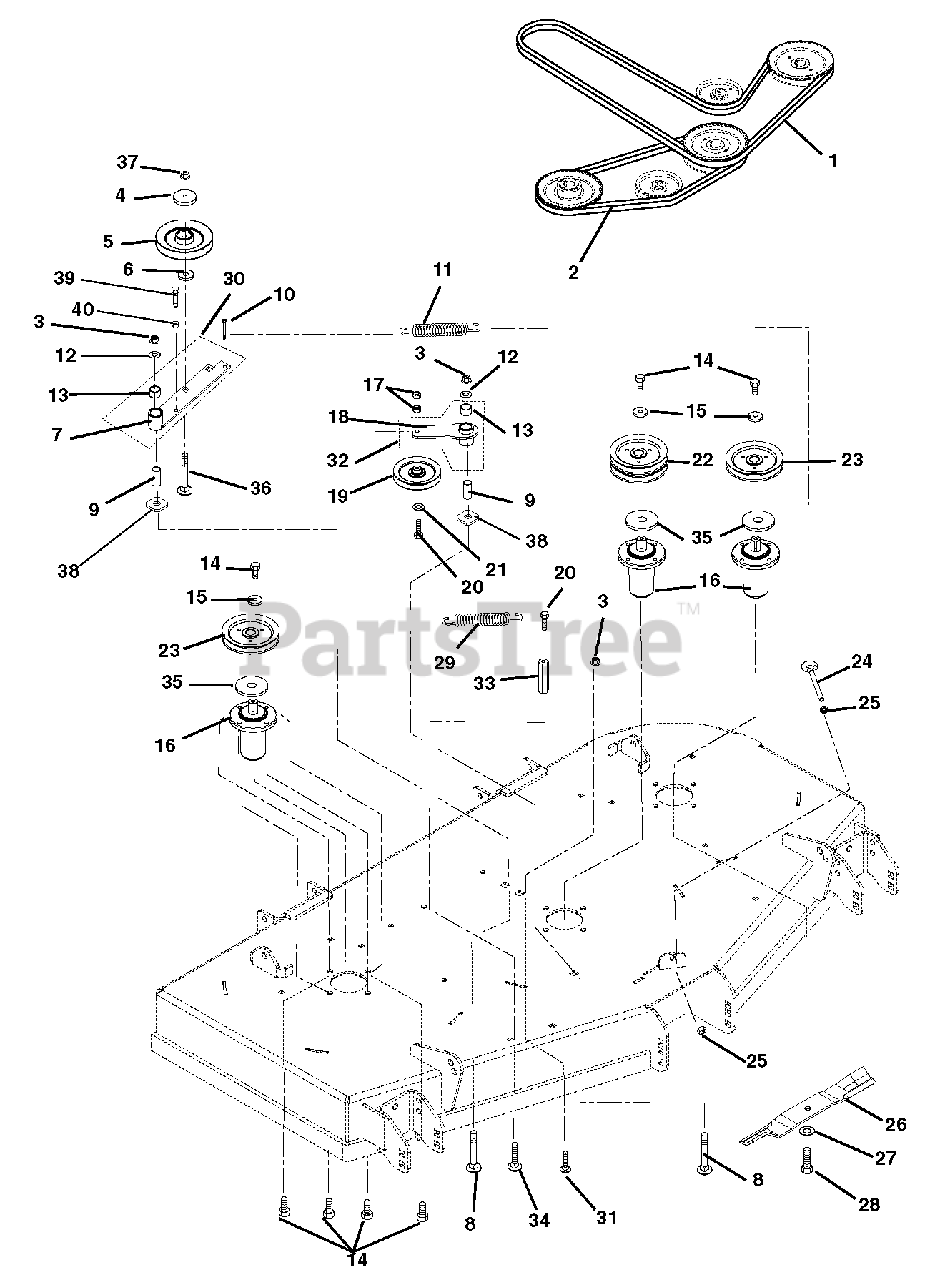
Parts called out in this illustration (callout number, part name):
1	Belt, 175" Long, PTO Drive Hex (992322)
2	V-Belt, 56" Long Cog B-Section (992322)
3	Nut, .50-13 Nyloc Flange
4	Cap, Idler Bearing Sealing
5	Pulley, V 6.0 x .500 ID SNGL. Bearing
6	Bushing, Spacer .502 x .997 x .50
7	Weldment, Idler Arm
8	Bolt, Round Head Square Neck .50-13 x 3.50 Grade 5
9	Bushing, Spacer .505/.500 x .999/.996 x 2.05/2.03
10	Bolt, Shoulder EP .38-16 x .30 Hex
11	Spring, Extension (Deck Idler)
12	Washer, Flat Steel .563 x 1.38 x .109
13	Bushing, 1.00 x 1.125 x 1.936
14	Bolt, Hex .38-16 x 1.00
15	Washer, Flat Steel .406 x 1.50 x .245
16	Spindle Assembly (321)
17	Nut, Locking Center .38-16
18	Weldment, Idler Arm
19	Sheave, .38"ID x 5.00"OD V-Idler
20	Bolt, Hex .38-16 x 2.25
21	Washer, Flat Steel .406 x .812 x .065
22	Sheave, Double 1" ID x 6.00" OD (992322)
23	Sheave, Single 1" ID x 6.00" OD (992322)
24	Bolt, .38-16 x 4.50 .62 Diameter Eye
25	Nut, Hex, Jam .375-16
26	Blade, 18.00" Mower, Mulch (992322)
27	Washer, Bellville .63 x 1.625 x.14
28	Bolt, Hex .62-18 x 1.75 Grade 8
29	Spring, Extension
30	Assembly, PTO Idler Pivot Arm (Includes item # 7 and item # 13)
31	Bolt, Round Head Square Neck .50-13 x 1.5, Full Thread, Grade 5
32	Assembly, Idler Pivot Arm (Includes item # 13 and item # 18 )
33	Nut, Coupling .375-16 x 1.75
34	Bolt, Round Head Square Neck .38-16 x 1.00
35	Retainer, Grease
36	Bolt, Round Head Square Neck .50-13 x 3.00 Grade 5
37	Nut, Locking Center .50-13
38	Washer, Flat .640 x 1.75 x .250
39	Bolt, Hex .38-16 x 2.75
40	Nut, Hex .38-16
